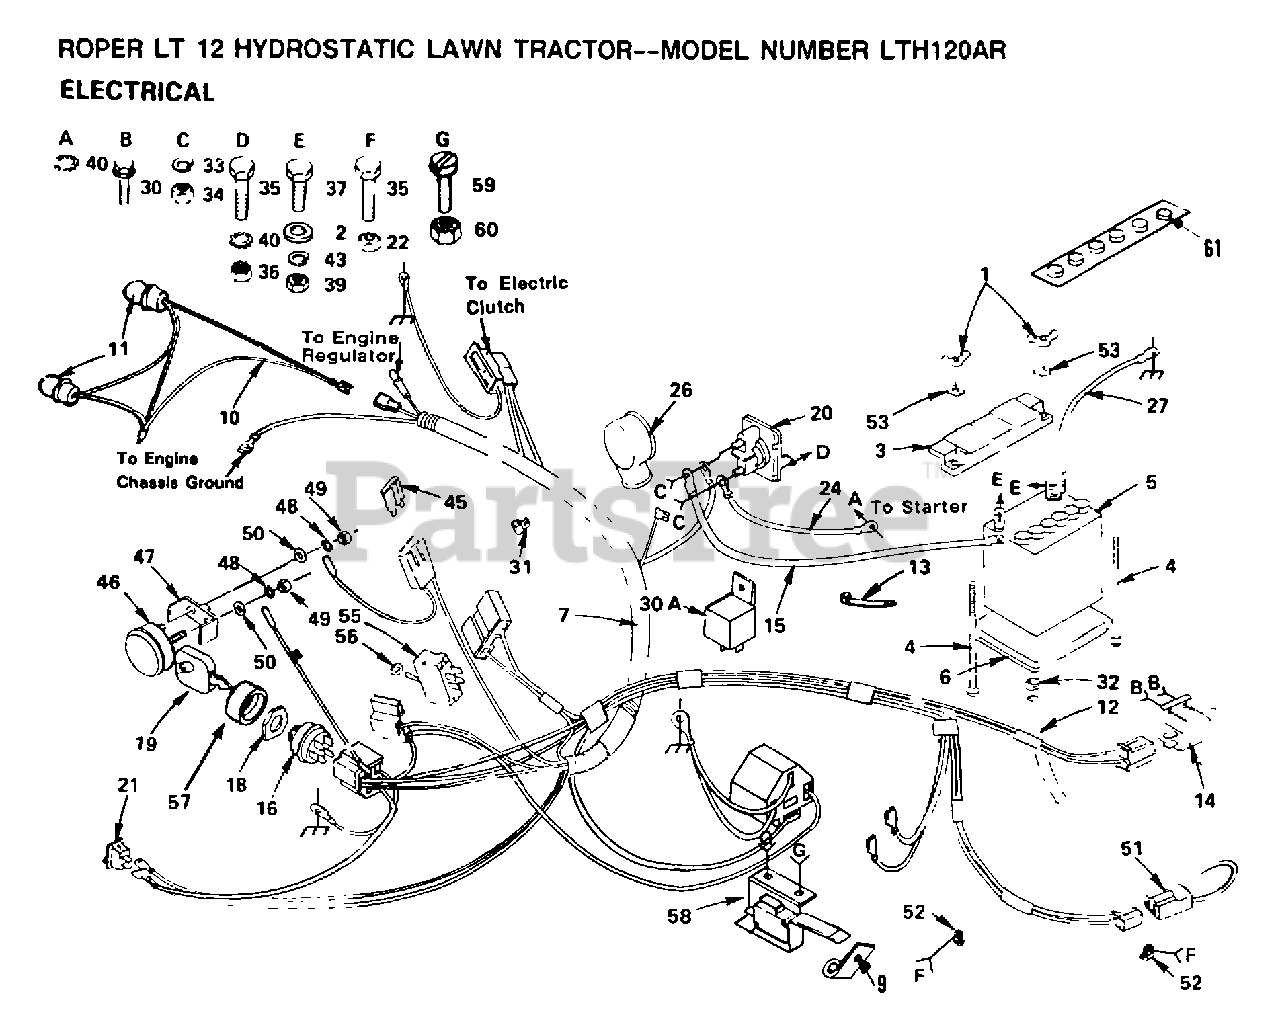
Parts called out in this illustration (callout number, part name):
2	WASHER
4	BOLT
6	"TRAY T, BATTERY"
10	HARNESS T
13	WIRE TIE
14	SWITCH-INTER. GT
15	CABLE-BATTERY T
21	SWITCH LT
24	CABLE-BATTERY T
27	CABLE T
30	SCREW
30A	RELAY ASSY T
31	CLIP T
32	HOSE CLAMP T
34	NUT
35	BOLT
36	NUT
37	BOLT LT
43	LOCKWASHER
45	FUSE HYT
46	AMMETER T
50	WASHER
52	CLIPT
53	LOCKWASHER GT
55	SWITCH.PTO.T
56	HEX NUT T
60	"NUT,KEPS"
61	BATTERY CAPS
